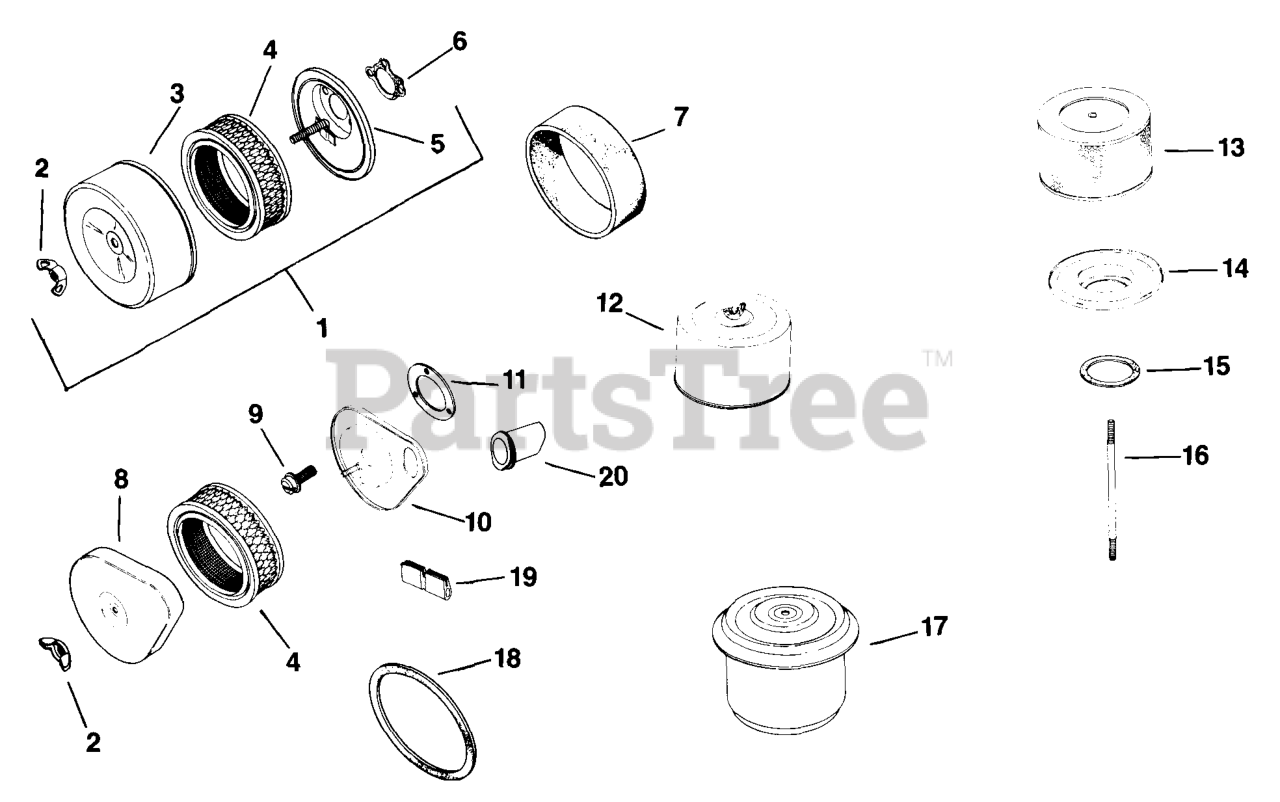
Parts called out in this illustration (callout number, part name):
1	CLEANER - DISCONTINUED
2	NUT, WING 1/4-20 USE 25 100 15-S
3	COVER, AIR CLEANER - DISCONTINUED
4	AIR FILTER/PRE-CLEANER KIT USE 25 883 03-S1
5	BASE, AIR CLEANER - DISCONTINUED
7	PRE-CLEANER USE 237421-S
7	PRE-CLEANER
